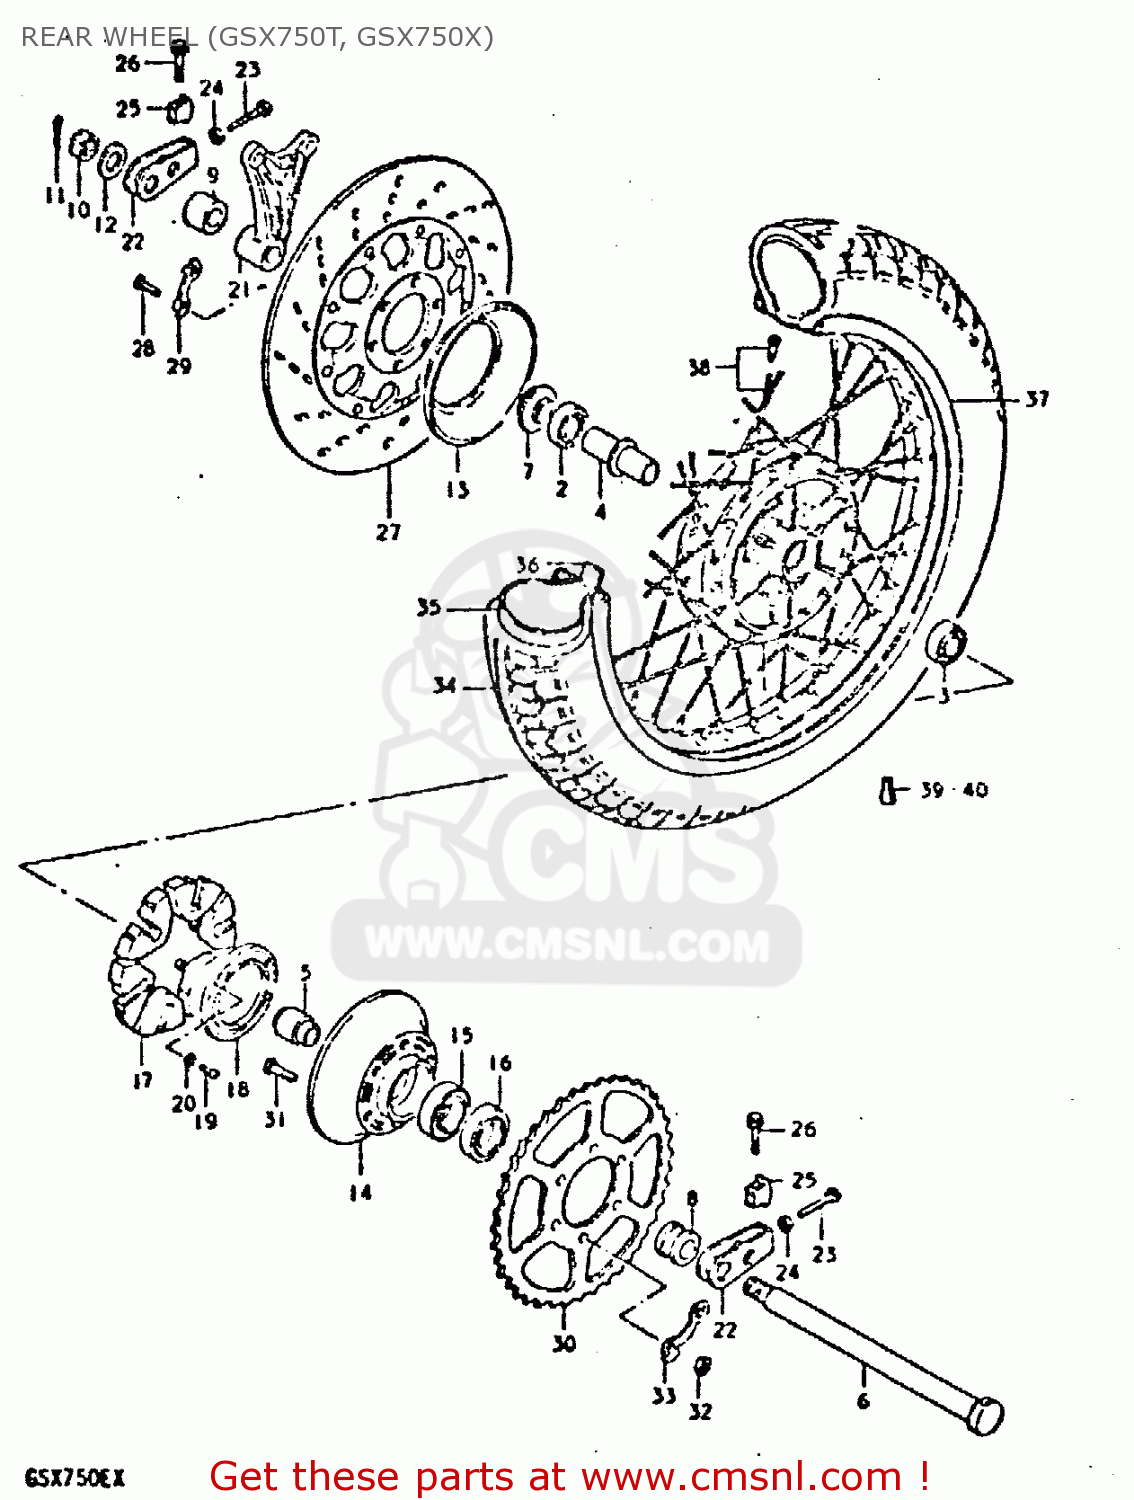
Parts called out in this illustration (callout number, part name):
1	DRUM,REAR HUB
2	BEARING
3	BEARING, LH
4	SPACER,REAR HUB BEARING
5	SPACER,REAR HUB BEARING
6	AXLE,REAR
7	SPACER,REAR AXLE
8	SPACER(20X33X28.3)
9	SPACER (20X38X17)
10	NUT 18MM
11	PIN,COTTER
12	WASHER(19X34X4)
13	COVER,REAR WHEEL HUB
14	DRUM,REAR SPROCKET MOUNT
15	BEARING
16	SEAL,OIL(33X62X7)
17	ABSORBER,REAR HUB SHOCK
18	PLATE,REAR HUB SHOCK ABSORBER
19	SCREW
20	LOCK WASHER
21	BRACKET,RR,CALIPER
22	ADJUSTER,CHAIN
23	BOLT
24	NUT
25	SUPPORTER,CHAIN ADJUST
26	BOLT (8X40)
27	DISC,RR BRAKE
28	BOLT(8X30)
29	WASHER
30	SPROCKET,RR
31	BOLT
32	NUT
33	WASHER
34	TIRE
35	TUBE,INNER
36	PROTECTOR,WHEEL,INNER
37	RIM,WHEEL
38	SPOKE SET
39	BALANCER,WHEEL (B)
40	BALANCER,WHEEL (30G)
